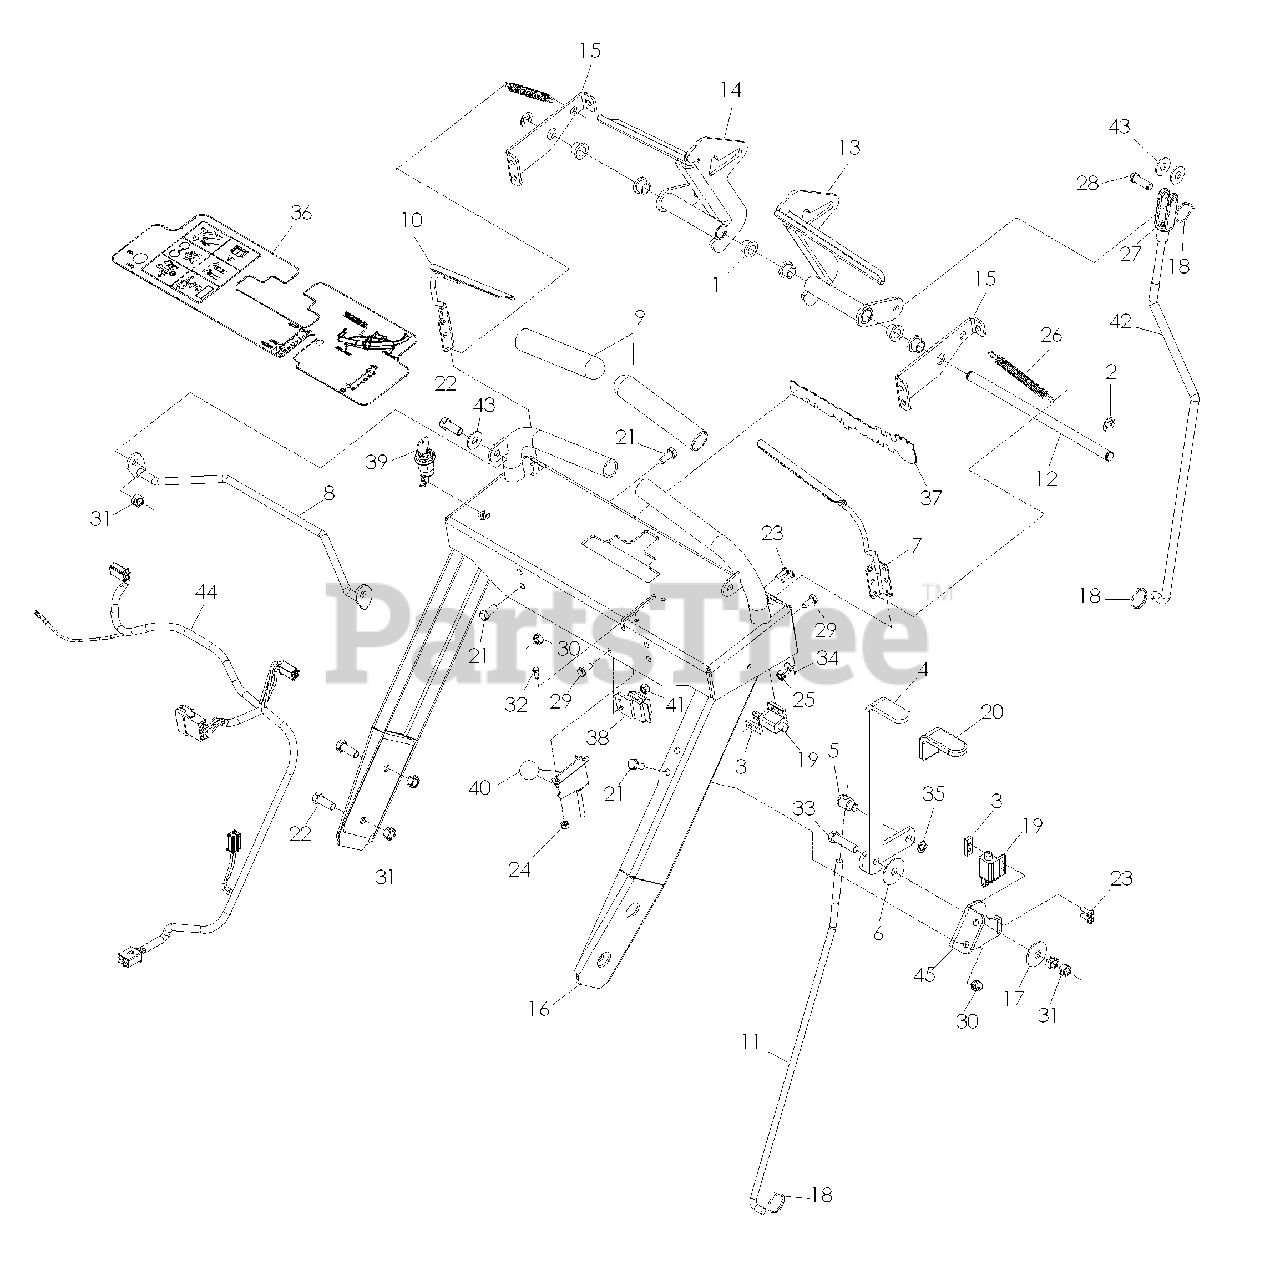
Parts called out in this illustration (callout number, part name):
1	BUSHING, FLANGED NYLON
2	E-RING 1/2"
3	TAPPED PLATE
4	ENGAGEMENT LEVER
6	WASHER, FRICTION
7	OP LEVER, LT.
8	NEUTRAL BAIL
10	OP LEVER, RT.
11	BLADE ENGAGE. LINKAGE
12	CENTER PIVOT SHAFT
13	DRIVE LEVER LT
14	DRIVE LEVER RT
15	SUPPORT BRACKET
17	WASHER,CONE
18	RETAINER RING
21	HCS 5/16-18 x 3/4
22	HCS 3/8-16 x 1
23	SCREW #10-24 x 5/8
24	NUT #10 NYLOC
25	NUT 1/4 LOCK
27	YOKE 3/8 -24
28	CLEVIS PIN
29	HCS 1/4 -20X 5/8
30	NUT 5/16-18 LOCK
31	NUT 3/8-16 LOCK
32	BOLT # 10 x 1/2
33	HCS 3/8-16 x 1 1/2
34	WASHER 1/4
35	RING, RETAINER
36	DECAL, CONSOLE
37	DECAL, HUSQVARNA
39	KEY SWITCH
40	THROTTLE CABLE
41	NUT 1/4-20 NYLOC
42	DRIVE LINKAGE
43	WASHER 3/8
44	UPPER HARNESS
45	BRACKET, BLADE ENGAGE
